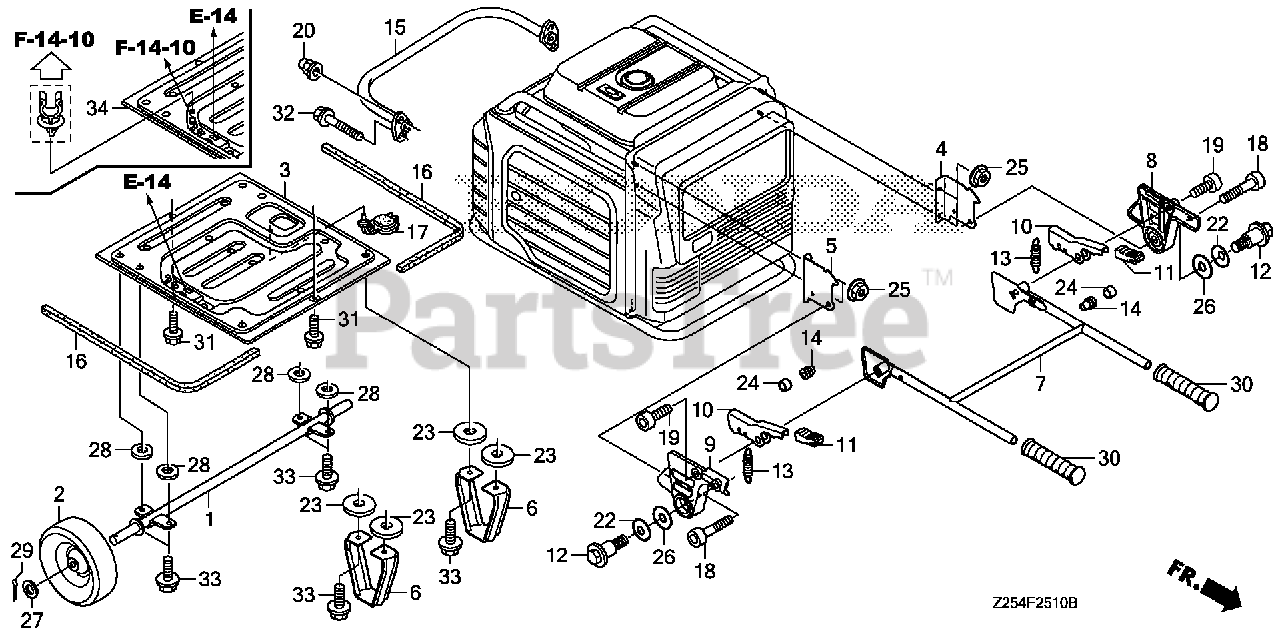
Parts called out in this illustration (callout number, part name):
1	SHAFT, WHEEL
2	WHEEL (250X60) (QINGDAO HUATIAN HAND TRUCK)
4	BRACKET, R. HANDLE
5	BRACKET, L. HANDLE
6	STAND *NH105* (MAT BLACK)
7	PIPE, HANDLE *NH105* (FOR U.S.A.) (MAT BLACK)
8	HOLDER, R. HANDLE
9	HOLDER, L. HANDLE
10	LEVER, HANDLE
11	RUBBER, GRIP
12	BOLT, HANDLE HOLDER
13	SPRING, HANDLE LEVER
14	RUBBER, STOPPER
15	PIPE, RR. *NH105* (MAT BLACK)
16	SEAL (8X8X705)
17	PLUG, OIL DRAIN
18	BOLT, SOCKET (8X45)
19	BOLT, SOCKET (8X22)
20	NUT, OPEN STAY (6MM)
22	WASHER, SPRING
23	WASHER, PLAIN (10.3X34)
24	COLLAR, HANDLE
25	NUT, FLANGE (8MM)
26	WASHER, PLAIN (12MM)
27	WASHER, PLAIN (20MM)
28	WASHER, PLAIN (8MM)
29	PIN, SPLIT (4.0X28)
29	PIN, SPLIT (4.0X30)
30	GRIP D, R. HANDLE (BOTH SIDES)
31	BOLT, FLANGE (6X16)
32	BOLT, FLANGE (6X30)
33	BOLT, FLANGE (8X25)
34	PLATE (LOWER)
